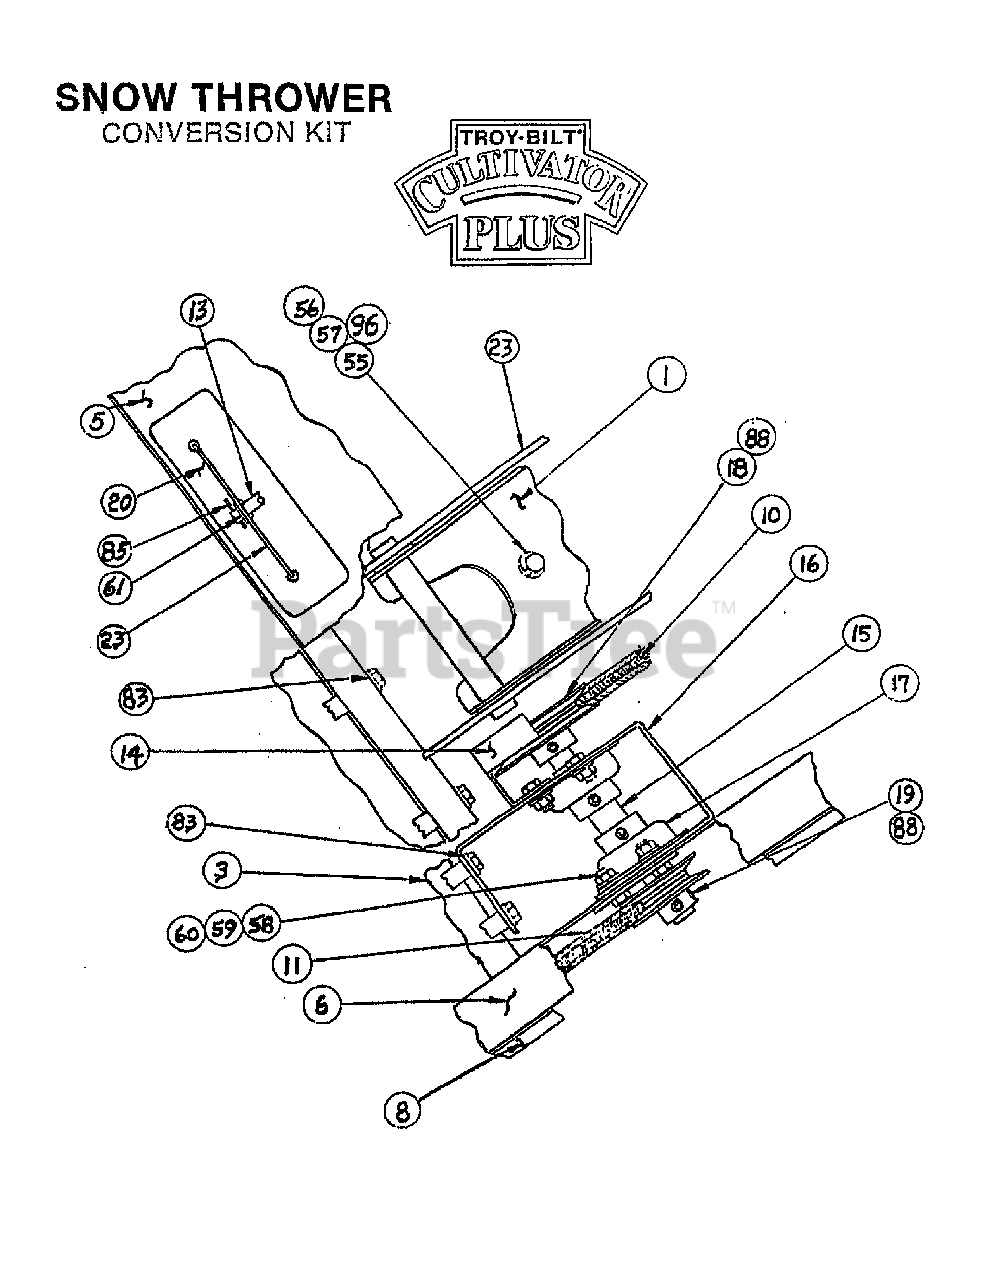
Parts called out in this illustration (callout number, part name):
3	WRAP SHEET W/DECALS
4	DEFLECTOR-VANE
5	MAIN GUARD W/DECAL
6	ASSM-SIDE PLATE LH
7	ASSM-PLATE RH
9	GUARD-DRIVE W/DECAL
10	BELT-V UPR DR SNOWBLOW
11	BELT-AUGER
12	BRKT-LOCKING PNT
13	DEFLECTOR-ROD WELD
15	SHAFT PICK-UP
16	BRKT-MOUNTING
18	PULLEY-ENGINE PICK-UP
19	PULLEY-AUGER DRIVE
20	SHIELD-WEATHER
21	ASSM-PIVOT VANE
22	ROD-LINKAGE
23	BRKT-MOUNTING WELD
24	HOLDER-IDLER WELD
25	PULLEY-IDLER
26	ASSM-IDLER PLATE
27	PLATE-MOUNTING
28	HANDLE-VANE CONTROL
29	GRIP-VANE CONTROL
30	PULLEY-ENGINE 4L
31	SPRING-COMPRESSION
32	ASSM-IDLER PULLEY
33	BUSHING-PIVOT
34	PULLEY-AUGER
35	STOP-OVERCENTER
36	GUIDE-BELT
38	ASSM-IDLER ARM
39	SPRING-AUGER STOP
42	ASSM-RECOIL GUARD
43	PLATE-AUGER
46	SUPPORT-AUGER
47	ASSM-BEARING
49	ASSM-SWITCH
50	COVER-CARB W/DECAL
51	D SPACER-IDLER
52	BOLT
53	WASHER
54	NUT
55	BOLT
56	WASHER
57	WASHER
58	BOLT
59	WASHER
60	NUT
61	WASHER
63	SCR-HH 5/16-18 X .20 STH ZP
64	BOLT
65	WASHER
66	NUT
67	RING-SNAP
68	WASHER-FLAT 3/4
69	SCR-RD HD #10-24 X 3/4
70	WASHER
71	NUT
72	SCR-HH 1/4-20 X 6
75	SCR-HEX TYPE A #10-.500
76	BOLT-HH 1/4-28 X 3/4
77	WASHER-1.06 X .25 X .067
78	KEY-WOODRUFF 1/8 X 1/2
79	BOLT
80	NUT
81	NUT
83	SCR-SHAKE PR 1/4-15 X 3/4
84	SCR-RH M10-24 X .50 ZP
86	CUSHION-6.74 5 LONG
87	CUSHION-3.75 LONG
88	KEY
89	PIN-HITCH ZP
90	KEY-.188 SQ X 1.25
91	SCR-HEX SOC FL #10-24
92	NUT
93	BRACE-SUPPORT
94	SCR-RD HD #8-32 X 5/8
95	NUT-LOCK #8-32
96	NUT
97	SCR-FLT HD 5/16-24
98	BOLT
99	PIN
102	LEVER-REMOTE CHOKE
103	WASHER
104	N KNOB-CHOKE LEVER
105	ENGINE STUD
106	SCR-HH 5/16-18X.63 G5
107	WASHER
110	CLAMP-CABLE
112	HINGE-SHROUD
113	WASHER
114	WASHER-FLAT 7/16 SAE
115	SCR-FLHH 5/16-24 X .75 ZP
117	DECAL-CARB COVER
118	DECAL-"CULTIVATOR-PLUS"
119	DECAL-WARN. BELT CVR
122	DECAL-DEFLECTOR PLT LT
123	DECAL-DEFLECTOR PLT RT
124	DECAL-ATTACH INST
126	DECAL-ANSI
